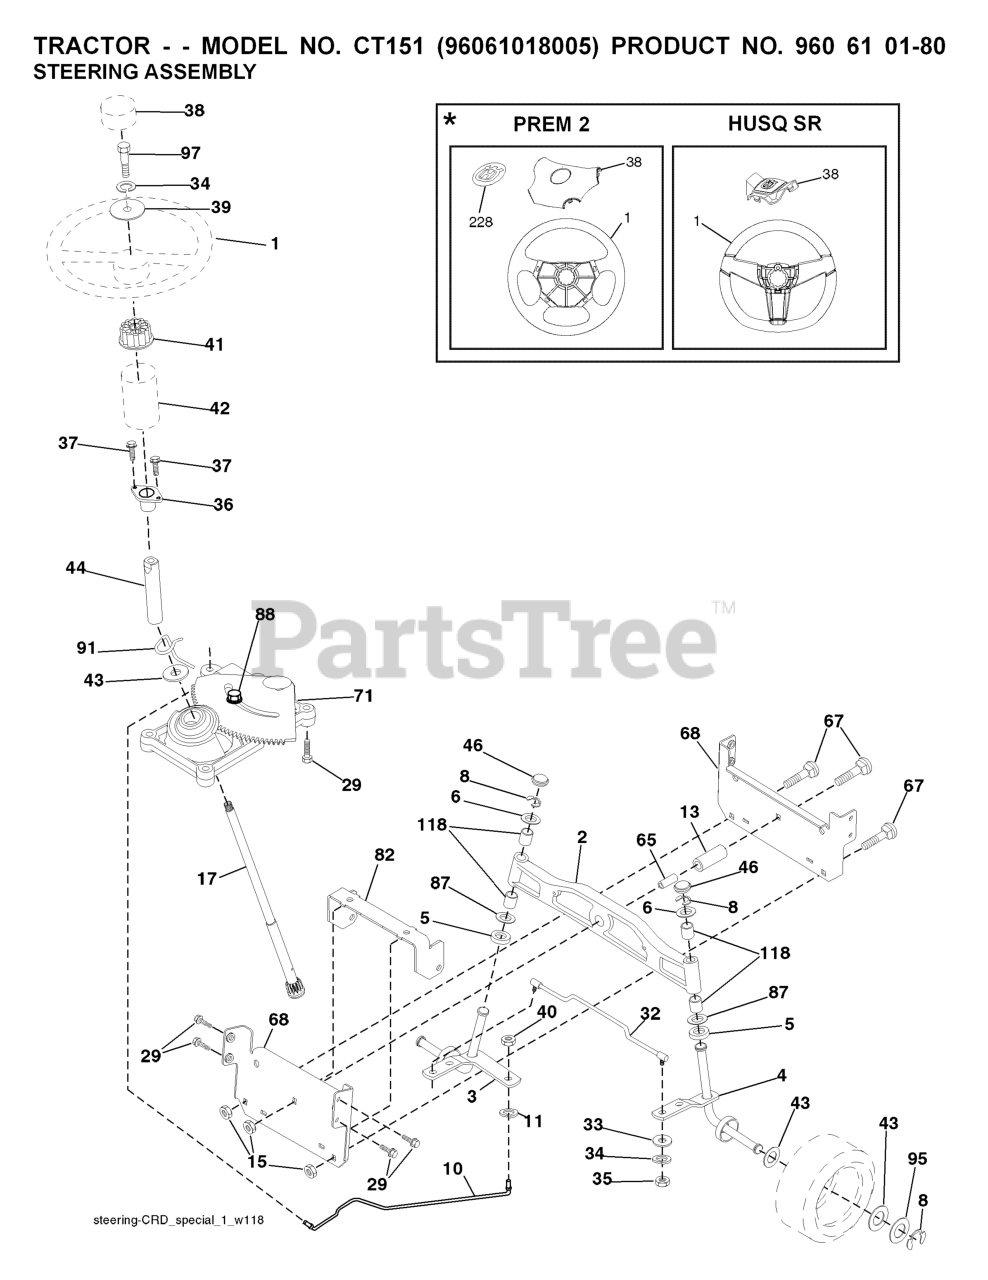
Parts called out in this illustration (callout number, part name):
1	RP WHEEL.STEER.HUSQ.PREM.OVMLD
2	AXLE ASSY FRONT
3	SPINDLE.ASM.LH.15"TIRES
4	SPINDLE.ASM.RH.15"TIRES
5	THRUST WASHER
10	DRAGLINK.15".TIRES.2001
11	WASHER, LOCK 3/8
13	TUBE, PIVOT AXLE
15	NUT
17	SHAFT STEERING SPLINE
29	SCREW, 3/8-16X3/4
33	WASHER M
34	WASHER.LOCK.HVY.HLCL.SPR.5/16
35	NUT, CROWNLOCK
36	BUSHING, STEERING
37	SCREW.TT.#10-32X.5.3/8.FLANGE
38	RP INSERT.CAP.WHL.STRG.HUSQ.
39	WASHER.11/32
40	NUT CROWNLOCK 3/8-24
41	ADAPTER, WHEEL STNG..
42	BOOT, STEERING
44	SHAFT.EXTEN.STRG.SPLINE
46	CAP.SPINDLE.BLACK
65	SPACER BRACE AXLE
67	BOLT CARRIAGE
68	BRACE.AXLE.15"TIRES
71	STEERING ASM
82	BRACKET.SUSP.CHASSIS.FRONT.15
87	WASHER, FLAT .781 X 1 1/2"
88	BOLT, SHOULDER 7/16-20
91	CLIP.STEERING
95	WASHER.HARDENED
118	BUSHING, AXLE CAST
228	DECAL.WHEEL.STRG.LGN.H
